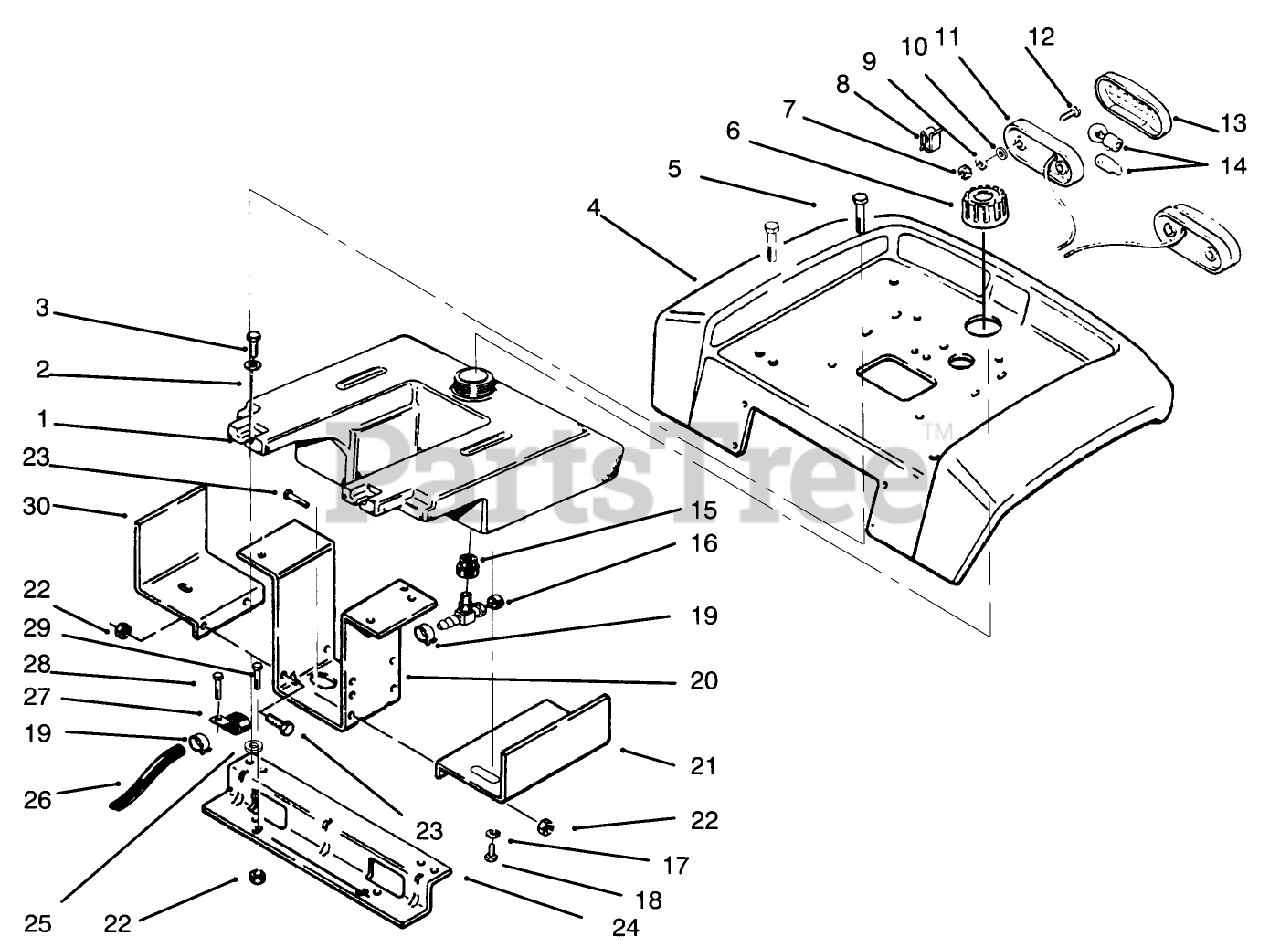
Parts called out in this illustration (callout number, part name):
1	TANK-FUEL
2	WASHER-FLAT
5	SCREW
6	GAS CAP ASM
7	NUT-LOCK, NI
9	WASHER-FLAT
10	WASHER-LOCK, INT
13	LENS-TAIL LIGHT
14	Bulb
16	VALVE-FUEL
17	WASHER-LOCK
18	SCREW-HH
19	CLAMP-HOSE
22	NUT-LOCK, NI
23	SCREW-HH
25	WASHER-PLAIN
27	CLIP
28	SCREW-HH, LOCK
29	SCREW-HH
